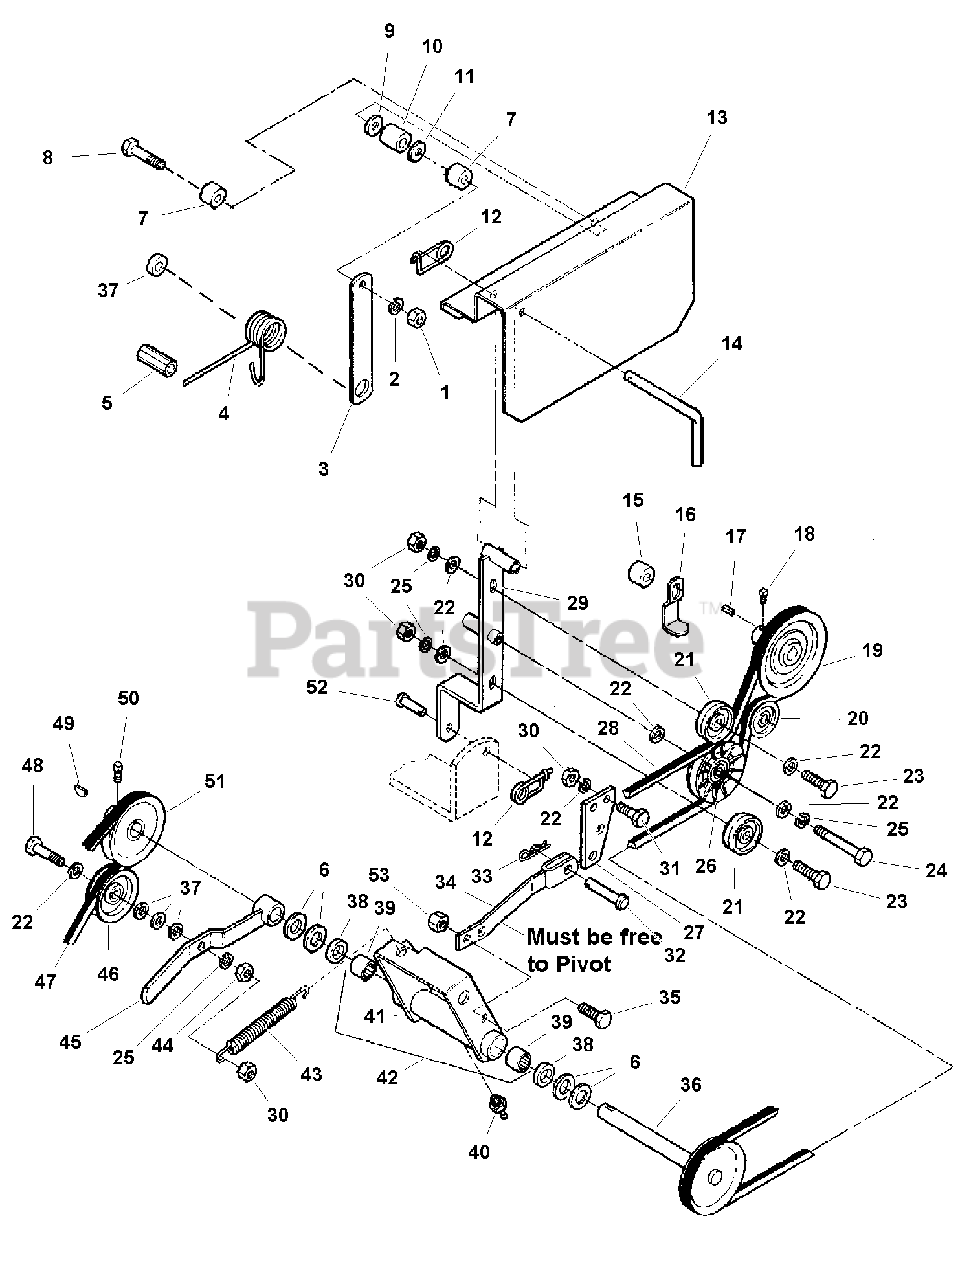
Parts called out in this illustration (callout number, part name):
1	NUT-HEX, 5/16-18
2	LOCKWASHER,5/16
3	SUPPORT, Rear Belt Guard
4	SPRING, Torsion
5	ANCHOR, Spring
8	CAPSCREW, Hex Head, 5/16-18 x 2-3/4
9	WASHER, Nylon
10	BUSHING
12	RETAINER PIN
13	COVER, Belt
16	GUARD, Spring
18	SCREW,Set Square Head, Cup Point, 3/8-16 x 1/2, G8
19	PULLEY, 9inch OD
20	PULLEY, Idler, 2-3/4 OD
21	PULLEY, Idler, 1-7/8 OD
22	WASHER
23	CAPSCREW,Hex Head, 3/8-16 x 1-3/4
24	CAPSCREWHex Head, 3/8-16 x 1-1/4
25	LOCKWASHER, 3/8
26	PULLEY, Idler, 4 OD
27	ANCHOR, Jackshaft
29	SHAFT & SUPPORT ASSEMBLY
30	NUT, Hex Center Lock Jam, 3/8-16
31	CAPSCREW, Hex Head, 3/8-16 x 1
32	PIN, Yoke, Drilled
33	CLIP, Hair Pin
34	CLEVIS & BAR ASSEMBLY, Anchor
35	CAPSCREW, Hex Head, 5/16-18 x 1
36	PULLEY & SHAFT ASSEMBLY
39	BEARING
40	FITTING, LUBE
42	CLEVIS & HOUSING ASSEMBLY, w/ Bearings (Includes Ref. Nos. 39 & 40)
43	SPRING, Extension
44	NUT, Hex, 3/8-16
45	ARM & HUB ASSEMBLY
46	PULLEY, Idler, 3-5/8 OD
48	CAPSCREW, Hex Head, 3/8-16 x 2
49	KEY, WOODRUFF, #61
50	SCREW, Set, Square Head Cup Point, 5/16-18 x 1/2, G8
51	PULLEY & HUB ASSEMBLY
52	PIN, Round Head, Drilled
53	NUT, Hex Centerlock, 5/16-18
